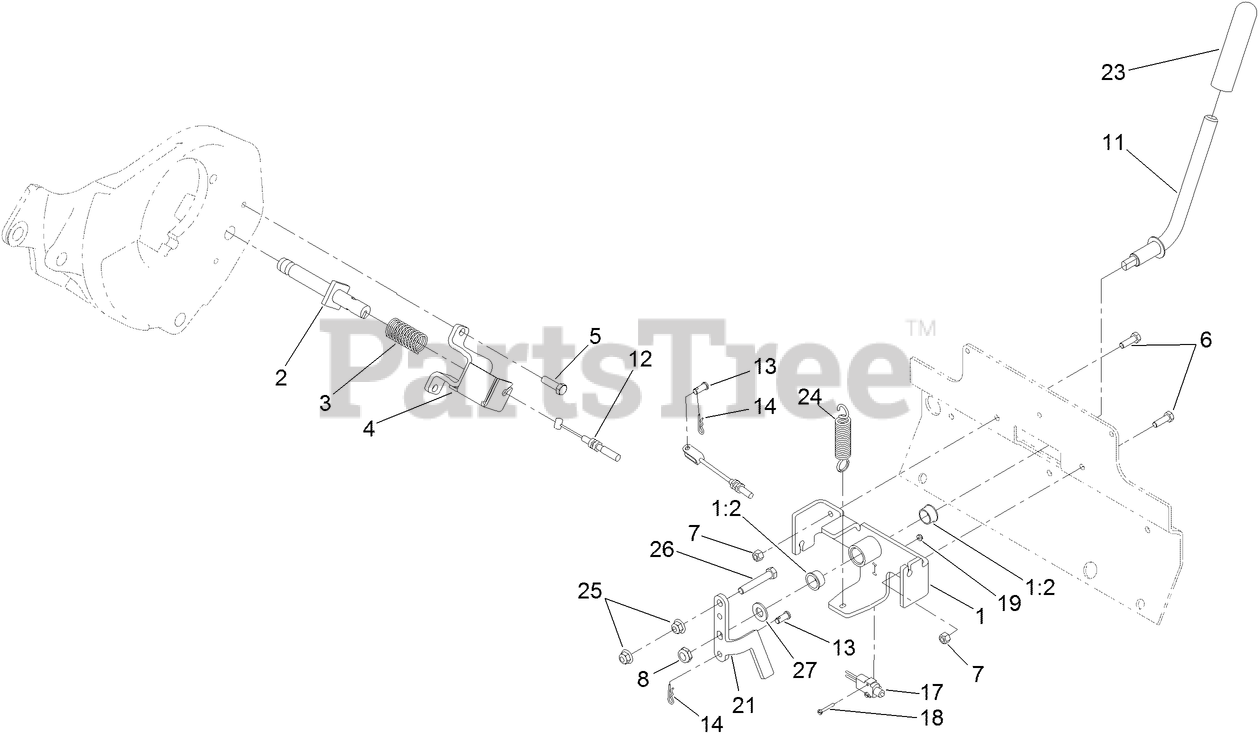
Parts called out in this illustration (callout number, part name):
1	BRAKE BRACKET ASM
1:2	BEARING-FLANGE
3	SPRING-COMPRESSION
4	BRACKET-BRAKE
5	SCREW-HH
6	SCREW-HH
7	NUT-LOCK, NI
8	NUT-LOCK, NI
11	LEVER-BRAKE
12	CABLE-BRAKE
13	PIN-CLEVIS
14	PIN-COTTER
17	SWITCH
18	SCREW
19	NUT-HEX
21	PLATE-LINKAGE, BRAKE
23	GRIP-HANDLE
24	SPRING-EXTENSION
25	NUT-HF, NI
26	SCREW-HH
27	WASHER-FLAT
